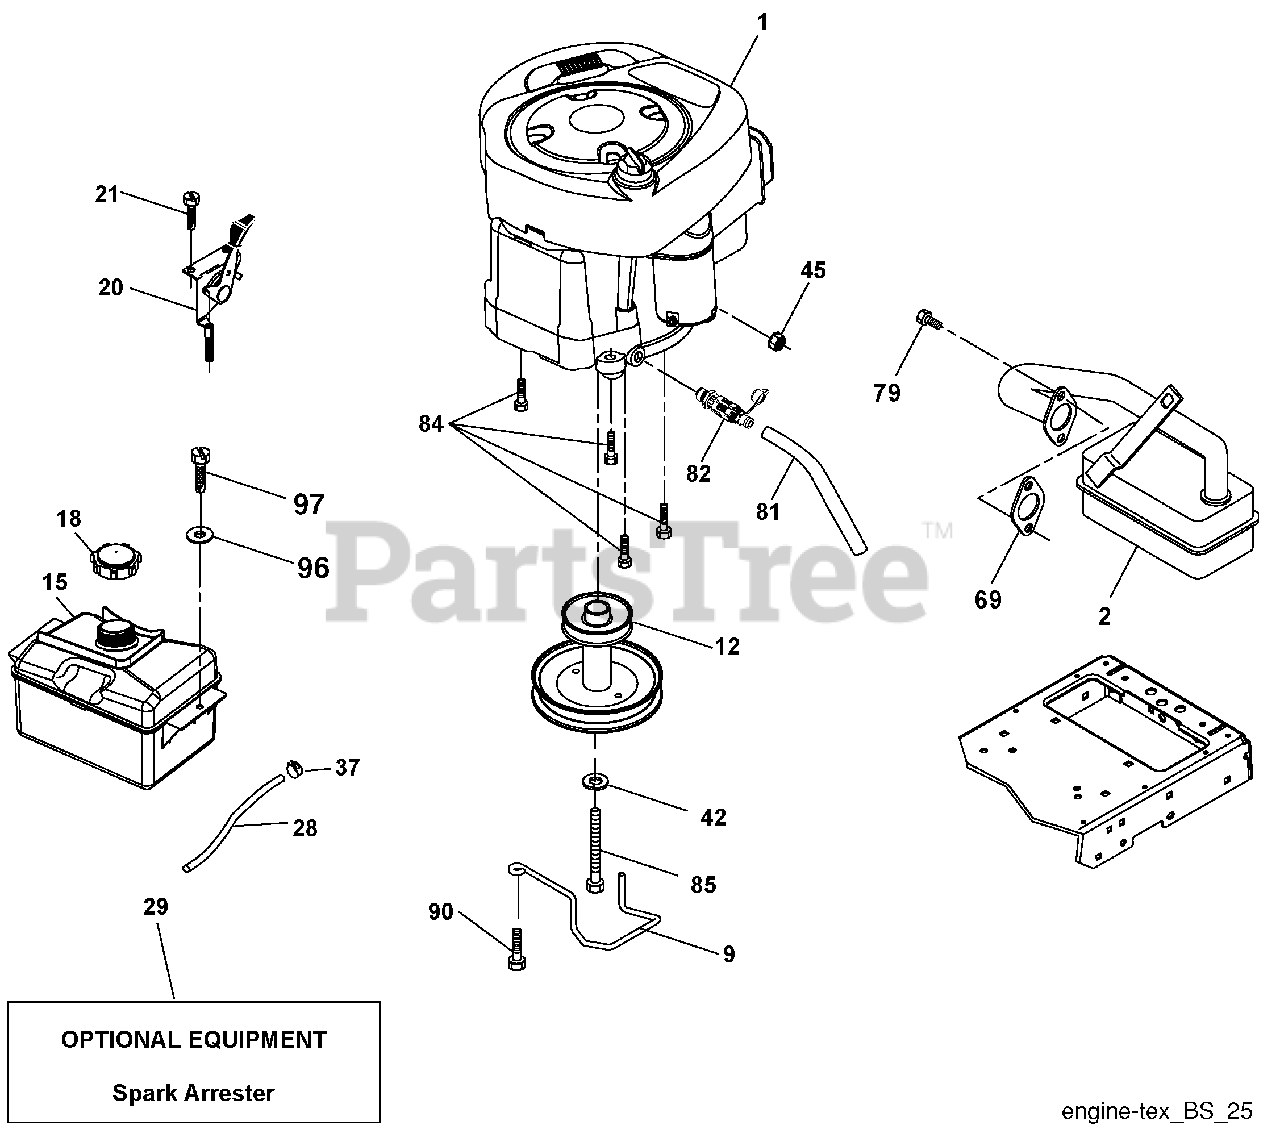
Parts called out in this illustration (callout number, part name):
2	Muffler
9	Keeper Belt Engine
12	Pulley Engine
15	Tank Fuel 1.50
18	Cap Fuel
20	Control Throttle/Choke
21	Screw #10 x 0.750
28	Fuel Line
29	Spark Arrester Kit
37	Clamp Hose
42	Washer Lock 7/16
45	Nut Keps Hex 1/4-20 unc
69	Gasket
79	Screw Socket Hd 5/16-18 x .75
81	Tube Drain Oil Easy
82	Valve Drain Oil
84	Screw 3/8-16 x 1-1/4
85	Bolt Hex 7/16-20 x 4 x Gr. 5-1.5
90	Screw 3/8-16 x 1.0
96	Washer 9/32 x 7/8 x 16 Ga.
97	Screw 1/4-20 x 3/4
